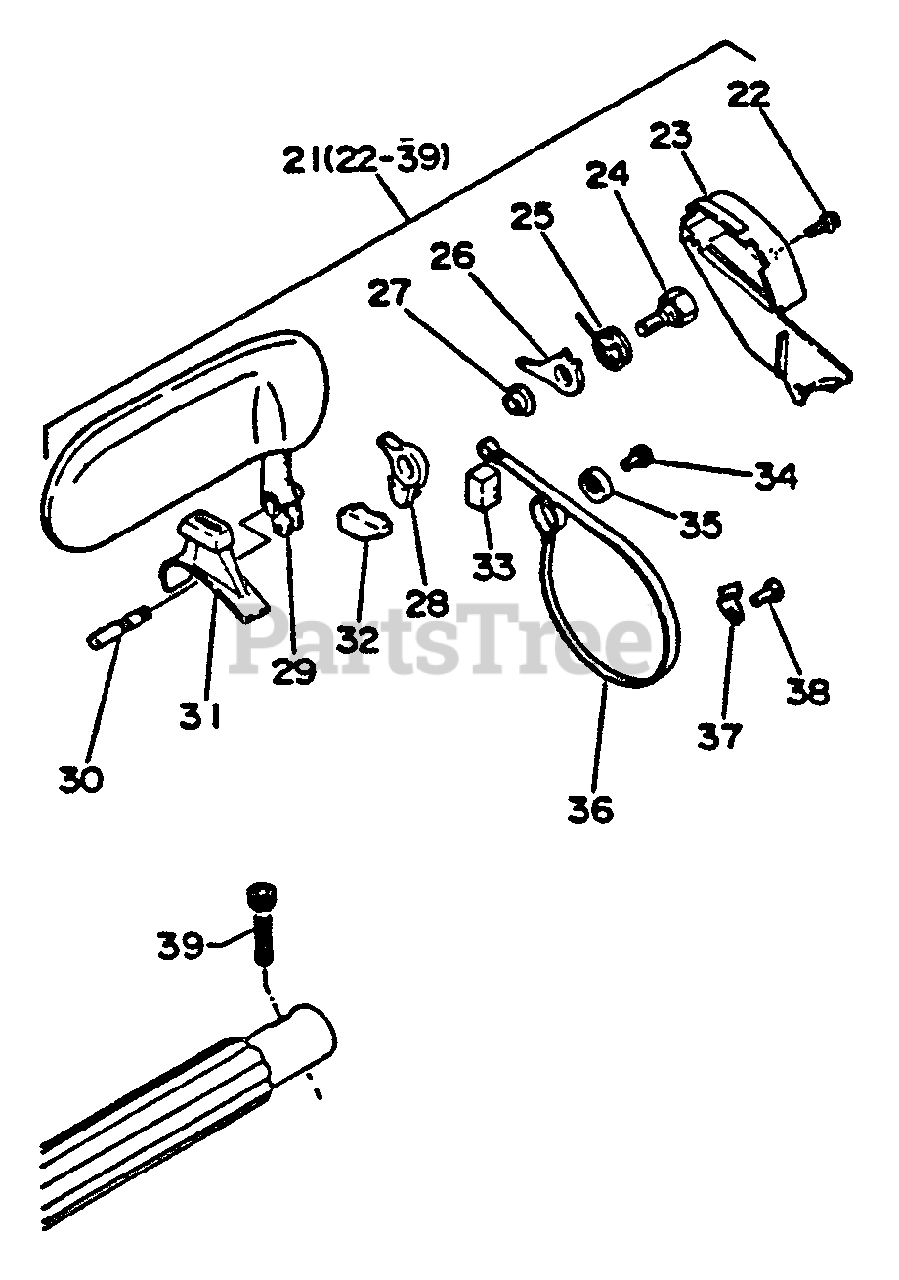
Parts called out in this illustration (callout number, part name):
21	CHAIN BRAKE ASSY
22	SCREW 4×10
23	COVER, BRAKE
25	SPRING, RETURN
28	CONNECTOR
29	HANDLE
31	COVER, BRAKE
32	RESET, BRAKE
33	SEAL
34	SCREW 5×10
35	ADJUSTER, BRAKE BAND
36	BAND, BRAKE
37	RETAINER, BRAKE BAND
38	SCREW 5×10
39	BOLT 5×25
